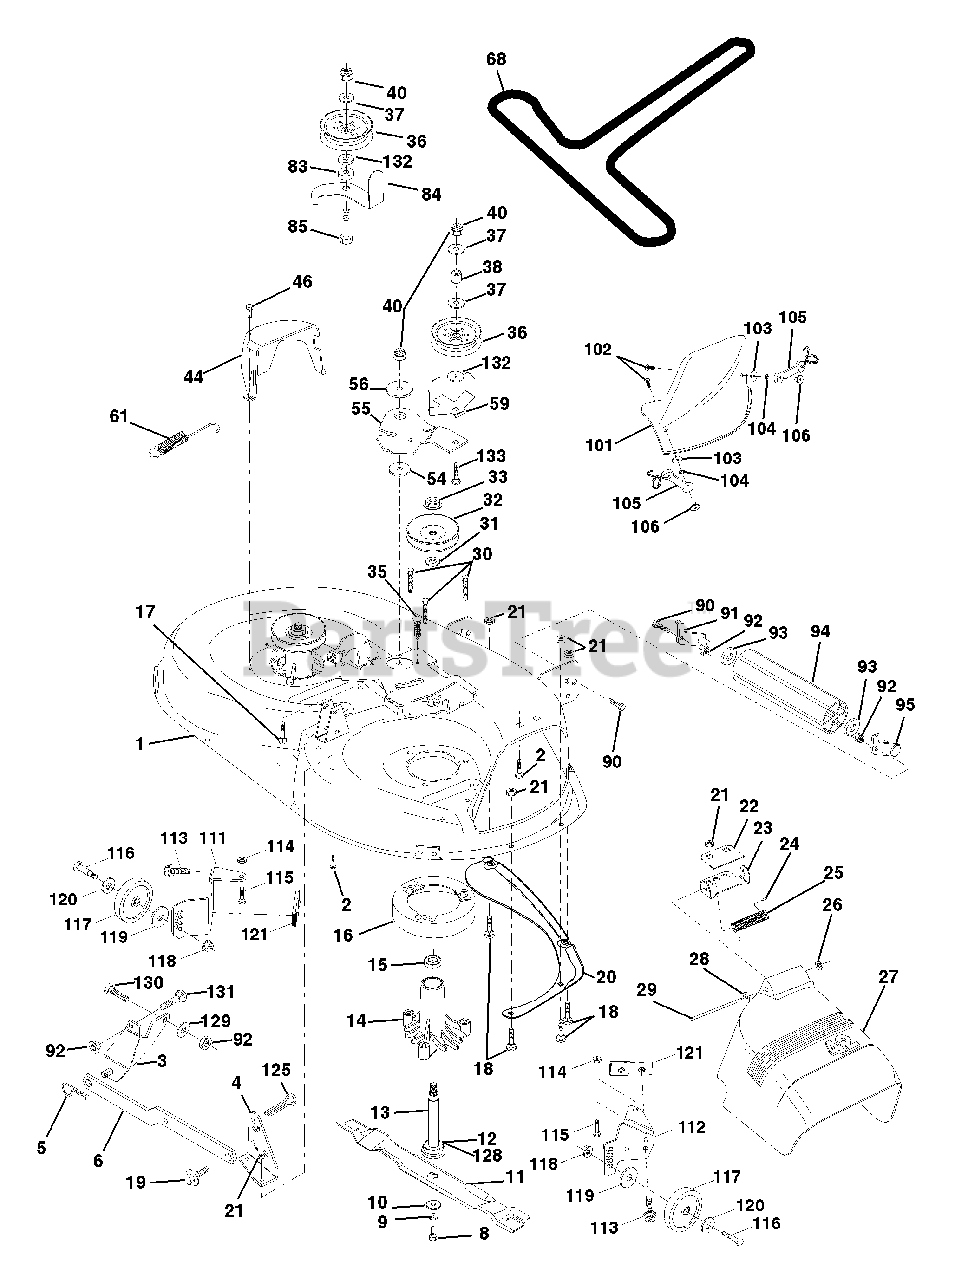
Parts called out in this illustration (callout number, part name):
1	Housing Asm Mower 42" 94 T-Path
2	Bolt Rdhd Sqnk 5/16-18 unc X 3/4
3	Bracket Asm Fr Sway Bar 38/42
4	Bracket Asm Deck 42" sway Bar
5	Retainer Spring
6	Arm Suspension Rear
8	Bolt 3/8-24 x 1 25 Gr 8 Patched
9	Washer Lock Hvy 3/8 Unplated
10	Washer Hard Blade Mower Vented
11	Blade Mower Mulching 42"
12	Bearing Ball #6204 (Mandrel)
13	Shaft Asm W/lower Bearing
14	Housing Mandrel Vented(machd)
15	Bearing Ball Mandrel
16	Stripper Round Mower
17	Bolt Rdhd Sqnk 3/8-16 X 2-1/4
18	Bolt Carr 5/16-18 X 5/8
19	Bolt Shoulder
20	Baffle Vortex 42
21	Nut Crown Lock 5/16-18
22	Stiffener Bracket 42" deck
23	Bracket Deflector Mower 42"
24	Cap Sleeve 80 x 112 Blk Mower
25	Spring Torsion Deflector 2 52
26	Nut Push Phos & Oil
27	Shield Deflector Mower 42" Blk
28	Washer 11/32 X 5/8 X 16 Ga
29	Rod Hinge 42" 6 75 Wlg
30	Screw Thdrol Washer Head
31	Washer Spacer Mower Vented
32	Pulley Mandrel 42"
33	Nut 9/16 top Lock Flng Cntr
35	Fastner Christmas Tree
36	Pulley Idler Flat 3 060
37	Washer 13/32 X 13/16 X 16 Ga
38	Spacer Spring Stop Idler
40	Nut Lock 3/8-16 Unc
44	Guard Mandrel LH Black
46	Screw Thdrol 1/4-20 x 5/8
54	Washer Hardened
55	Arm Idler 42" mower LT/YT
56	Spacer Retainer Pm Mower
59	Guard, Belt
61	Spring Ext. Elect
68	V-Belt Mower
83	Washer Sintered
84	Keeper Belt Idler
85	Bolt Carriage 3/8-16 x 2-1/4 Gr.5
90	Bolt Fin Hex 3/8-16unc X 1
91	Bracket Asm Noseroller LH
92	Nut Lock Hex w/ins. 3/8-16 UNC
93	Washer 17/32 X 7/8 X 16 Ga
94	Roller Nose 38 & 42
95	Bracket Asm Noseroller RH
101	Cover Mulching 42" Blk
102	Screw
103	Washer #10
104	Washer Lock #10
105	Latch Asm Bagger
106	Nut Weld .327/.304 #10-24
111	Bracket Wheel Gauge Lh 42" Deck
112	Bracket Gauge Wheel Rh 42" Deck
113	Screw Thdrol 5/16-18 x 3/4 TYT
114	Nut Keps 5/16 - 18 UNC
115	Bolt Carriage 5/16 - Unc x 1/2
116	Bolt Shld "A" 2.41 "B" 1.66
117	Wheel Gauge blk. 4.93
118	Nut Centerlock 3/8 - 16 UNC
119	Washer 3/8 x 7/8 x 14 Ga.
120	Washer 17/32 x 15/16 x 12 Ga.
125	Cotter Pin
128	Washer Felt
129	Washer 13/32 x 13/16 x 12 Ga.
130	Bolt Fin Hex 3/8-16 UNC x 1 Gr. 5
131	Bolt RDHD SQNK 3/8-16 UNC x 1
132	Washer 13/32 x 1-3/8 x 3 Ga
133	Bolt RDHD 3/8-16 UNC x 2-3/4 Gr.5
